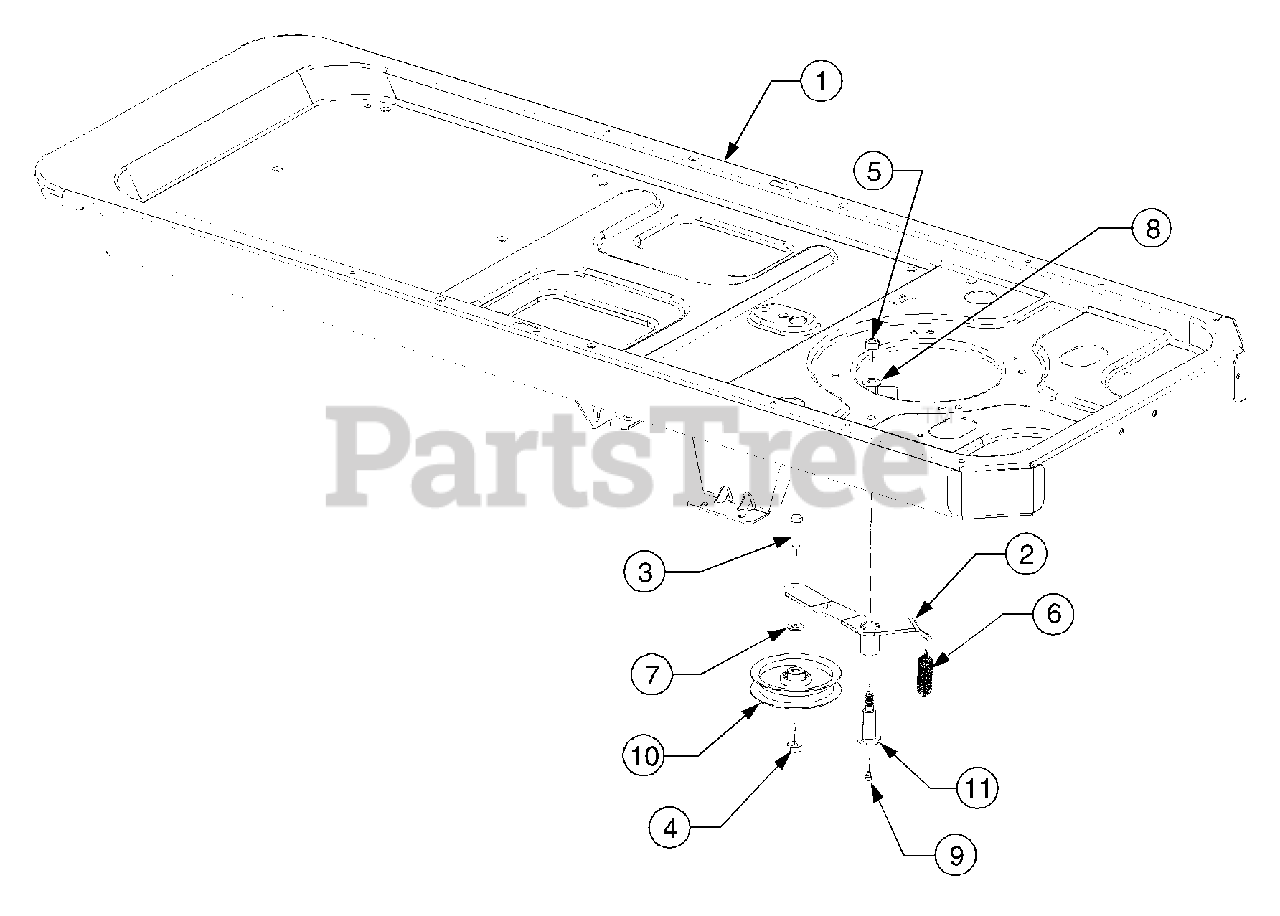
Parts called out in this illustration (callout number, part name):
4	Nut, Hex Flange Lock, 3/-16 GRF
5	Nut, Hex Lock, 7/16-14 GRA
6	Spring, Extension, .75 x 5.06
7	Washer, Flat, .406 x .875 x .059
8	Washer, Flat, .45 x 1.25 x .164 HT
9	Fitting, Lube, 3/16 Drive
10	Pulley, Idler, 4.08 Dia.
11	Screw, Shoulder, .68 x 1.59
